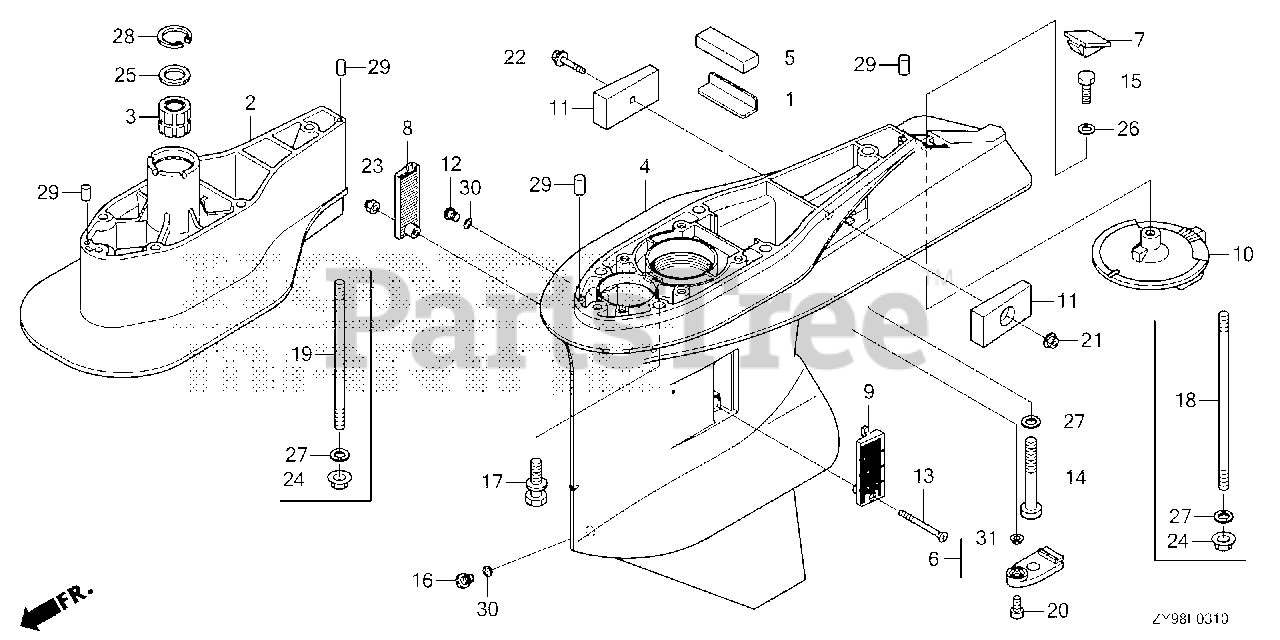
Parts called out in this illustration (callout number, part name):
1	PLATE, RUBBER SETTING
2	SEPARATOR, EXTENSION *NHB14M* (XL) (AQUA MARINE SILVER METALLIC)
3	BUSH, VERTICAL SHAFT
4	CASE, GEAR *NHB14M* (AQUA MARINE SILVER METALLIC)
5	GROMMET, GEAR CASE
6	COVER B, GEAR CASE
7	GROMMET, GEAR CASE
8	SCREEN, R. WATER
9	SCREEN, L. WATER
10	TAB, TRIM *NHB14M* (AQUA MARINE SILVER METALLIC)
11	METAL, ANODE
12	BOLT, OIL CHECK
13	SCREW, FLAT (5X55)
15	BOLT, HEX. (8X25)
16	BOLT, DRAIN PLUG
18	BOLT, STUD (10X202)
19	BOLT, STUD (10X164)
20	BOLT, SOCKET (6X16)
21	NUT, SELF-LOCK (6MM)
22	BOLT, FLANGE (6X35)
23	NUT, SELF-LOCK (5MM)
24	NUT, SELF-LOCK (10MM)
25	WASHER (26MM)
26	WASHER, PLAIN (8MM)
27	WASHER, PLAIN (10MM)
28	CIRCLIP (INNER) (40)
29	PIN, DOWEL (6X10)
30	O-RING (6.9X1.45)
31	COLLAR, DISTANCE (6.5X9X3)
